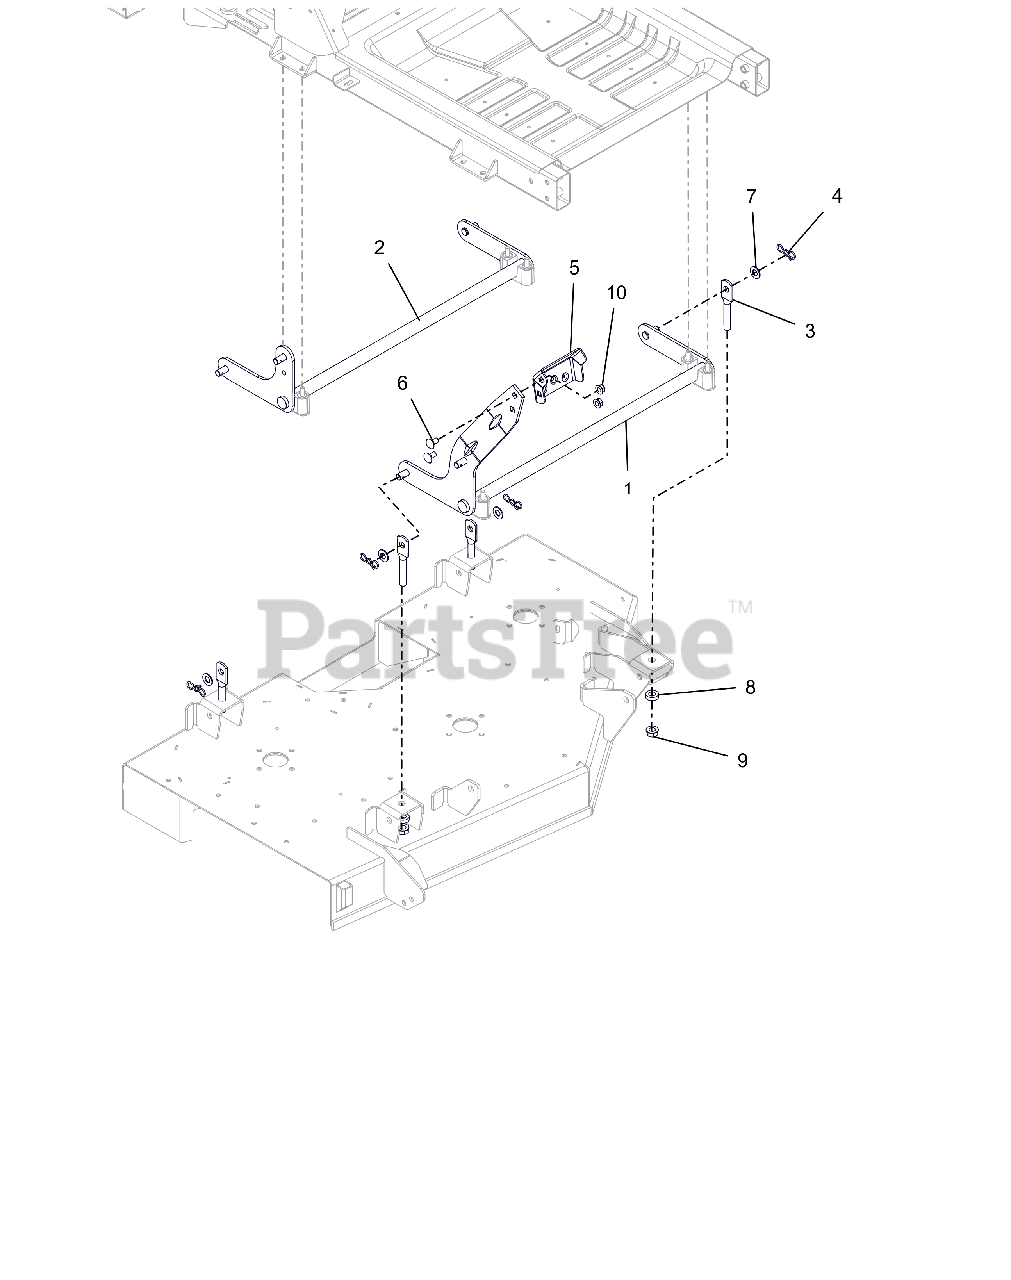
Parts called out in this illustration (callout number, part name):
1	WLDMT, FRONT DECK LIFT PIVOT
2	WLDMT, REAR DECK PIVOT
3	LINK, DECK (HOLE-SHORT)
4	PIN, BOWTIE .091X1.875 ZCC
5	PEDAL, DECK LIFT (BOLT ON)
6	BLT,RHSN .38-16X.75 G5 BFP
7	WSHR-FL-NYL .518X1.000X.080
8	WASHER, RUBBER
9	NUT-LK-CTR-FLG .500-13 GG ZCC
10	NUT-LK-CTR-FLG .375-16 GF ZCC
